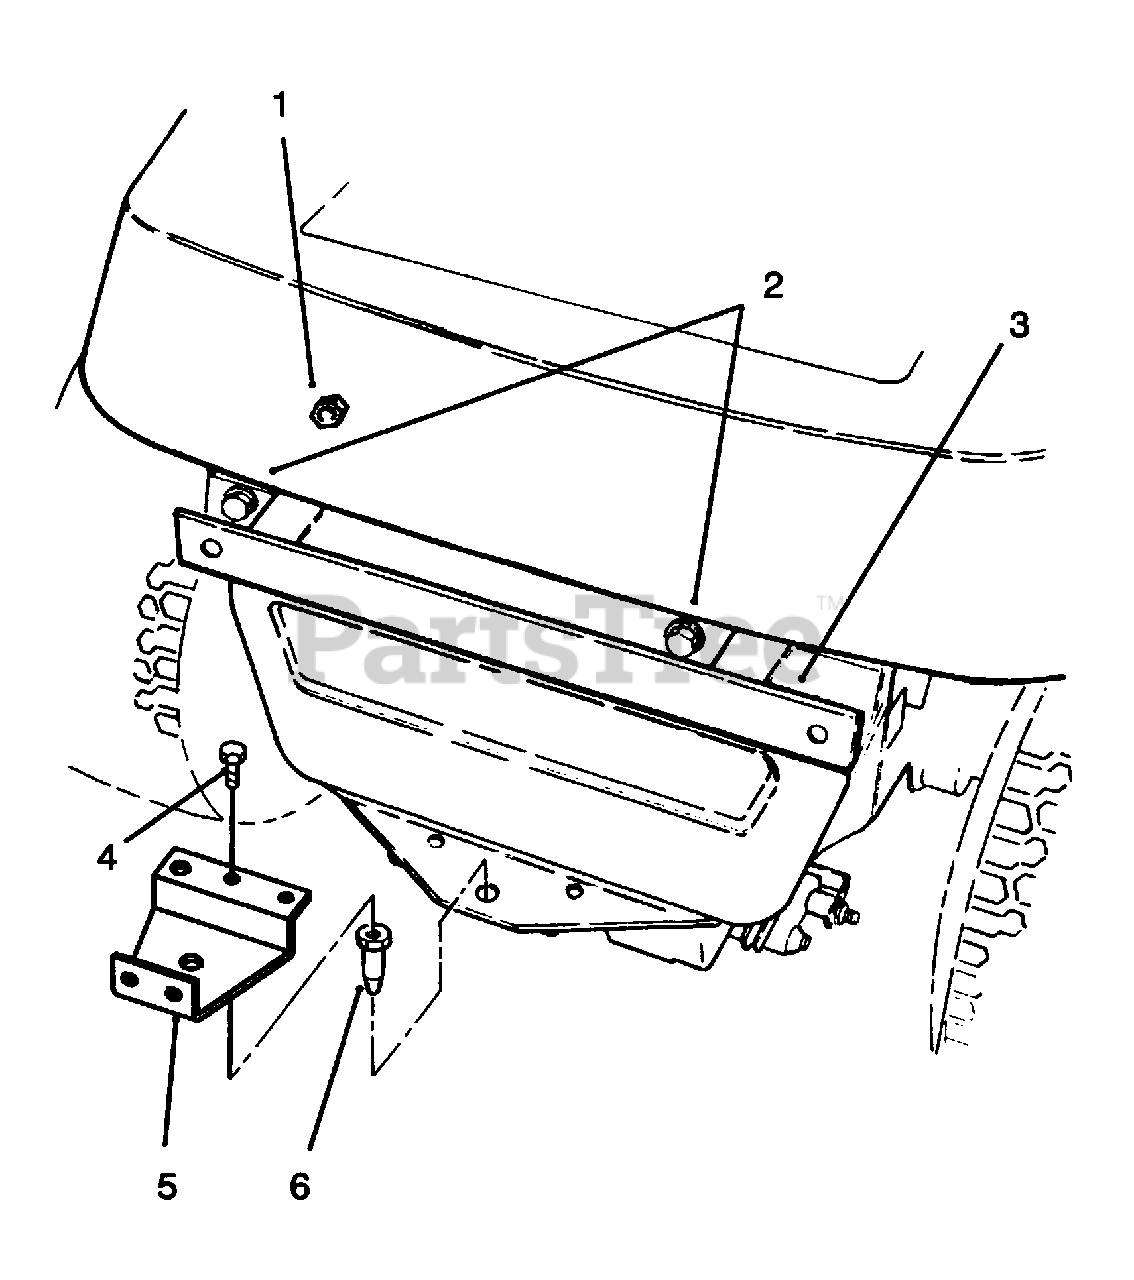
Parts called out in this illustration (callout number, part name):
2	Capscrew
3	Bracket-Channel
4	Capscrew
5	Bracket-Bagger Mounting
6	Pin-Mounting, Lower
